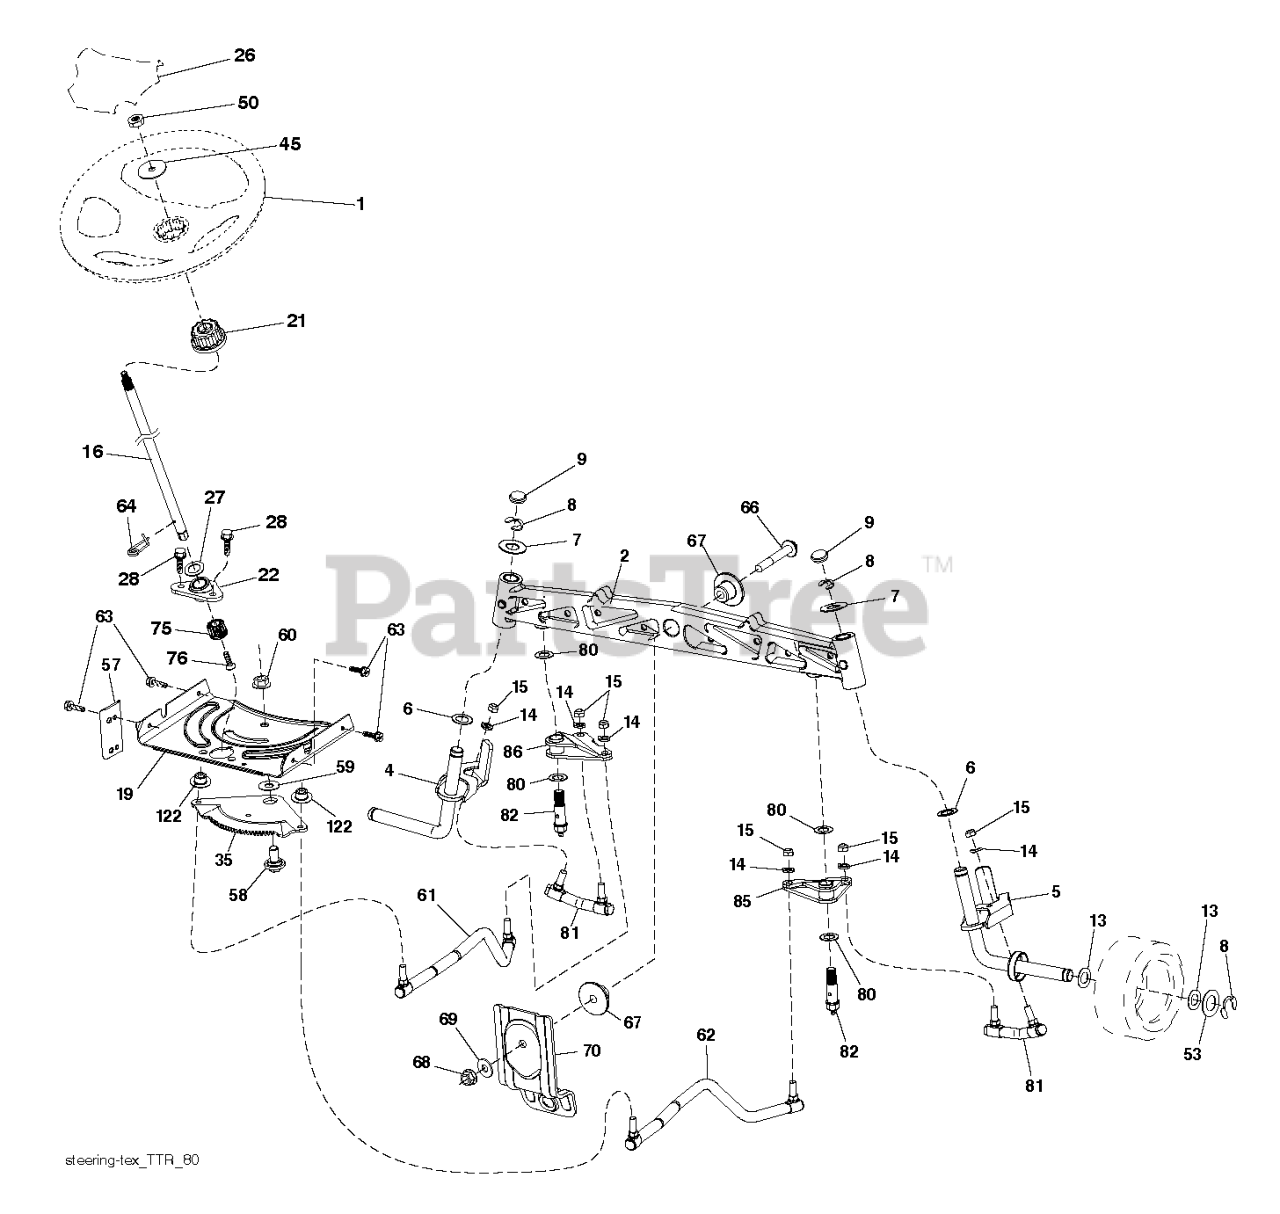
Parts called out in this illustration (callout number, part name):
1	WHEEL.STEER.HUSQ.SR.498.OVMLD
2	RP SUBASM.AXLE.CAST.NZTR.
4	SPINDLE WELDMENT.SPINDLE.LH.15
5	SPINDLE WELDMENT.SPINDLE.RH.15
6	THRUST WASHER
9	CAP.SPINDLE.BLACK
14	WASHER, LOCK 3/8
15	NUT CROWNLOCK 3/8-24
16	SHAFT.STEER.2HIGH.SPLND.PLATED
19	PLATE.STEER.DDL.NLT/NG
21	ADAPTER.WHEEL.STEER.SPLND.ALUM
22	BEARING.SUBASM.SHAFT.STEER.LOW
26	INSERT.CAP.WHL.STRG.HUSQ.PREM
27	WASHER LT
28	SCREW, 3/8-16X3/4
35	GEAR GEAR.SECTOR.TEX.NZTR
45	WASHER.3/8ID.2-3/8OD.12GA.PLTD
50	NUT LOCK FLG 3/8-16 UNC
53	WASHER.HARDENED
57	BRKT.UPSTOP.GT/LT.TEX
58	BOLT.SHOULDER.SECTOR.P
59	WASHER.THURST.SECTOR.S
60	NUT FLANGE LOCK 5/8-11
61	LINK SUBASM.LINK.DRAG.LH.NZTR
62	TUBE TUBE
63	SCREW
64	RETAINER.CLIP.SPRING.S
66	BOLT HEX FGHD 7/16-14 X 3 SERR
67	BUSHING.PM.FRONT AXLE
68	NUT.LOCK.FLANGE.7/16
69	WASHER.1.5X.505X.118
70	BRACKET.FRT.DECK.SUSP.RR.MT431
75	PINION.ZINC PLATED
76	SCREW HEAD SOCKET LRVB
80	THRUST WASHER
81	LINK SUBASM.LINK.CROSS.NZTR
82	SUBASM;PIVOT;BOLT;NZTR
85	PIVOT SUBASM.PIVOT.RH.NZTR
86	PIVOT SUBASM.PIVOT.LH.NZTR
122	CAP.GEAR.SECTOR.TEX
